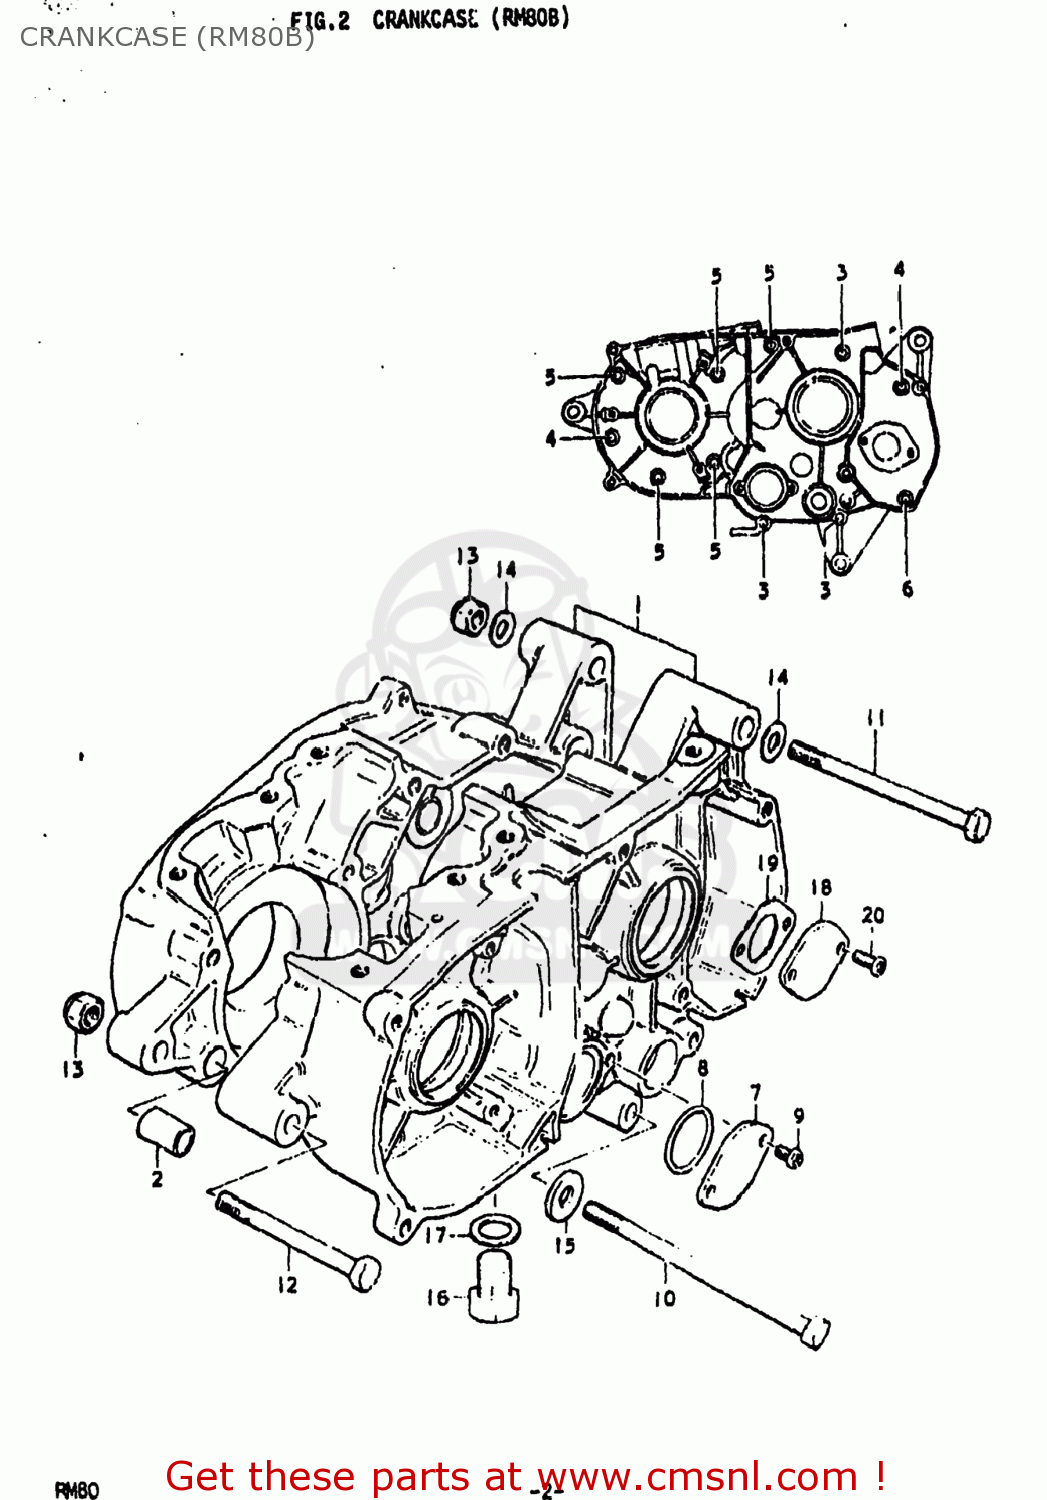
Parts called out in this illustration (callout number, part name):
1	CRANKCASE SET
2	PIN
3	SCREW
4	SCREW (6X45)
5	SCREW (6X35)
6	SCREW
7	CAP,GEAR SHIFT CAM PIVOT
8	O-RING (D:2.4 ID:26.2)
9	SCREW
10	BOLT
11	BOLT 8X100
12	BOLT,8X75
13	NUT
14	WASHER
15	WASHER
16	PLUG
17	GASKET(14X19.2X2) (NAS)
18	CAP,OIL PUMP DRIVE SHAFT
19	GASKET,OIL PUMP (MCA)
20	SCREW
